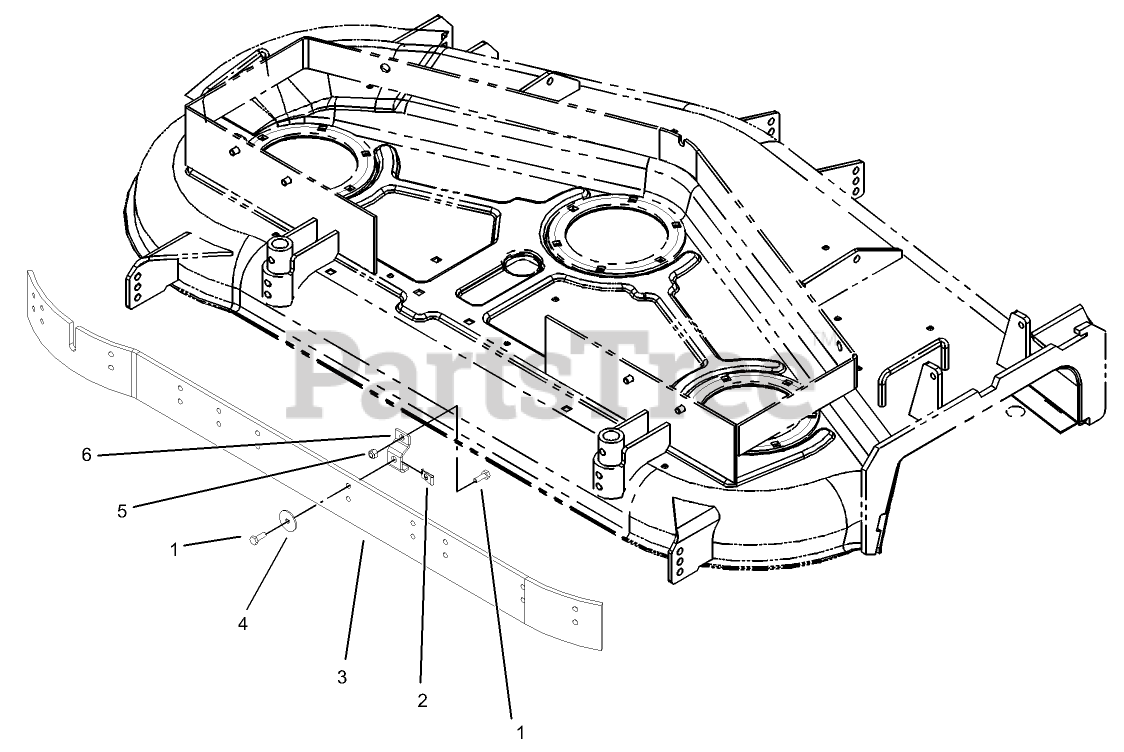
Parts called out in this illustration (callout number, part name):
1	SCREW-HH
2	NUT-SPEED
3	Wiper-Stiping Kit
4	WASHER-FLAT
5	NUT-LOCK, NI
6	BRACKET - MOUNTING
